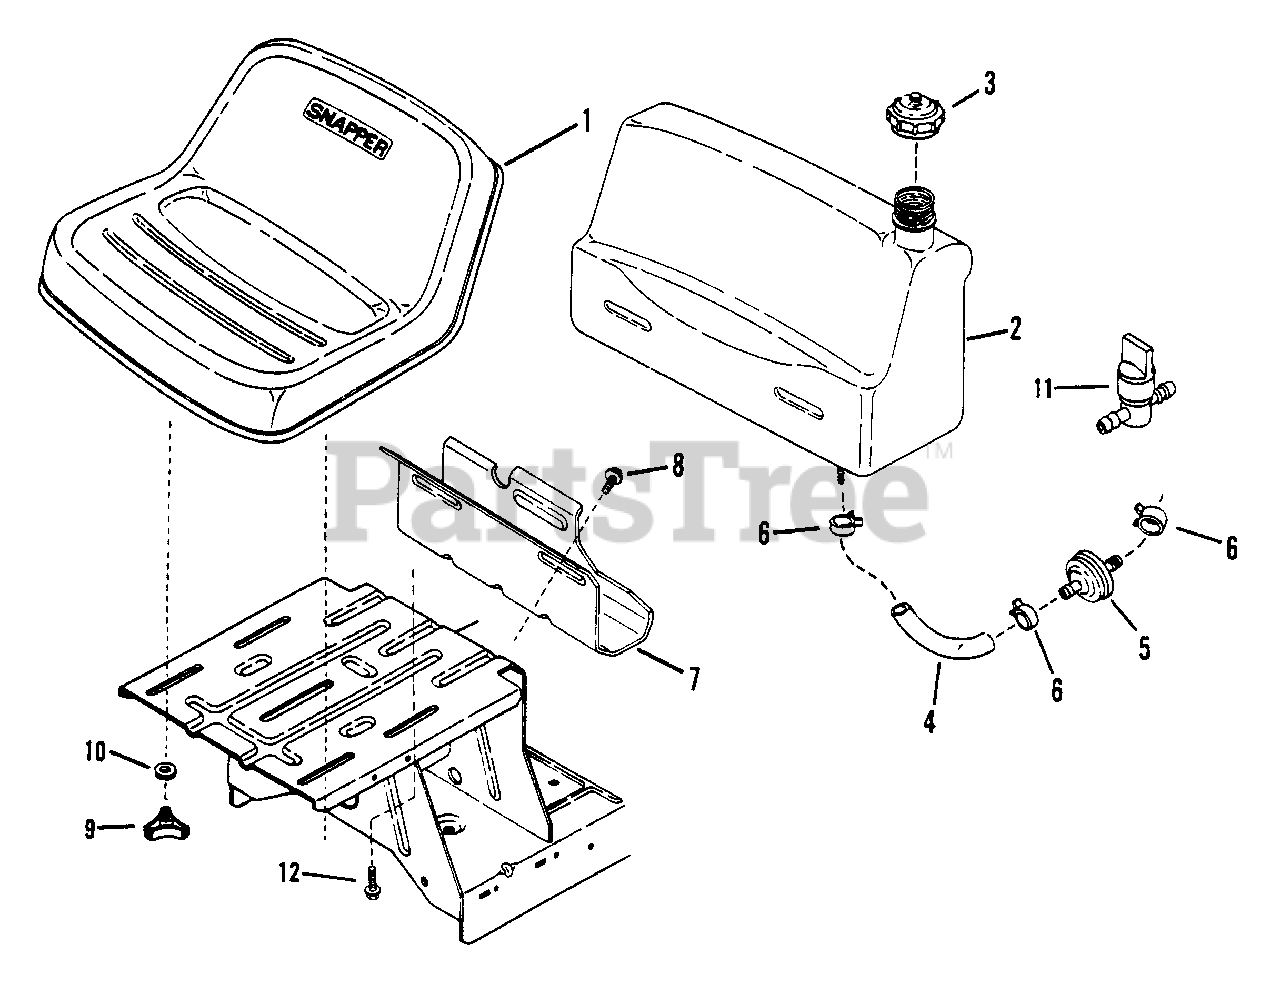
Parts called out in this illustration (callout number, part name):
1	SEAT, Operator (Low Back)
1	SEAT, Operator (Mid Back)
1	SEAT, Operator (Deluxe Back)
2	ASSEMBLY, Fuel Tank
3	CAP, Fuel Tank
4	HOSE, Fuel (7" Long)
4	HOSE, Fuel (5" Long)
4	HOSE, Fuel (8-1/2" Long)
4	HOSE, Fuel (12-1/2" Long);
5	FILTER, Fuel (In-Line)
6	CLAMP, Fuel Line
7	BRACKET, Fuel Tank (Rear)
8	SCREW, 5/16-18 x 5/8" Self-Tapping
9	KNOB, Seat Adjusting
10	SPACER, 5/16
11	VALVE, Fuel Shut-Off
12	BOLT, 5/16-18 x 1/2" Hex Flange Lock
